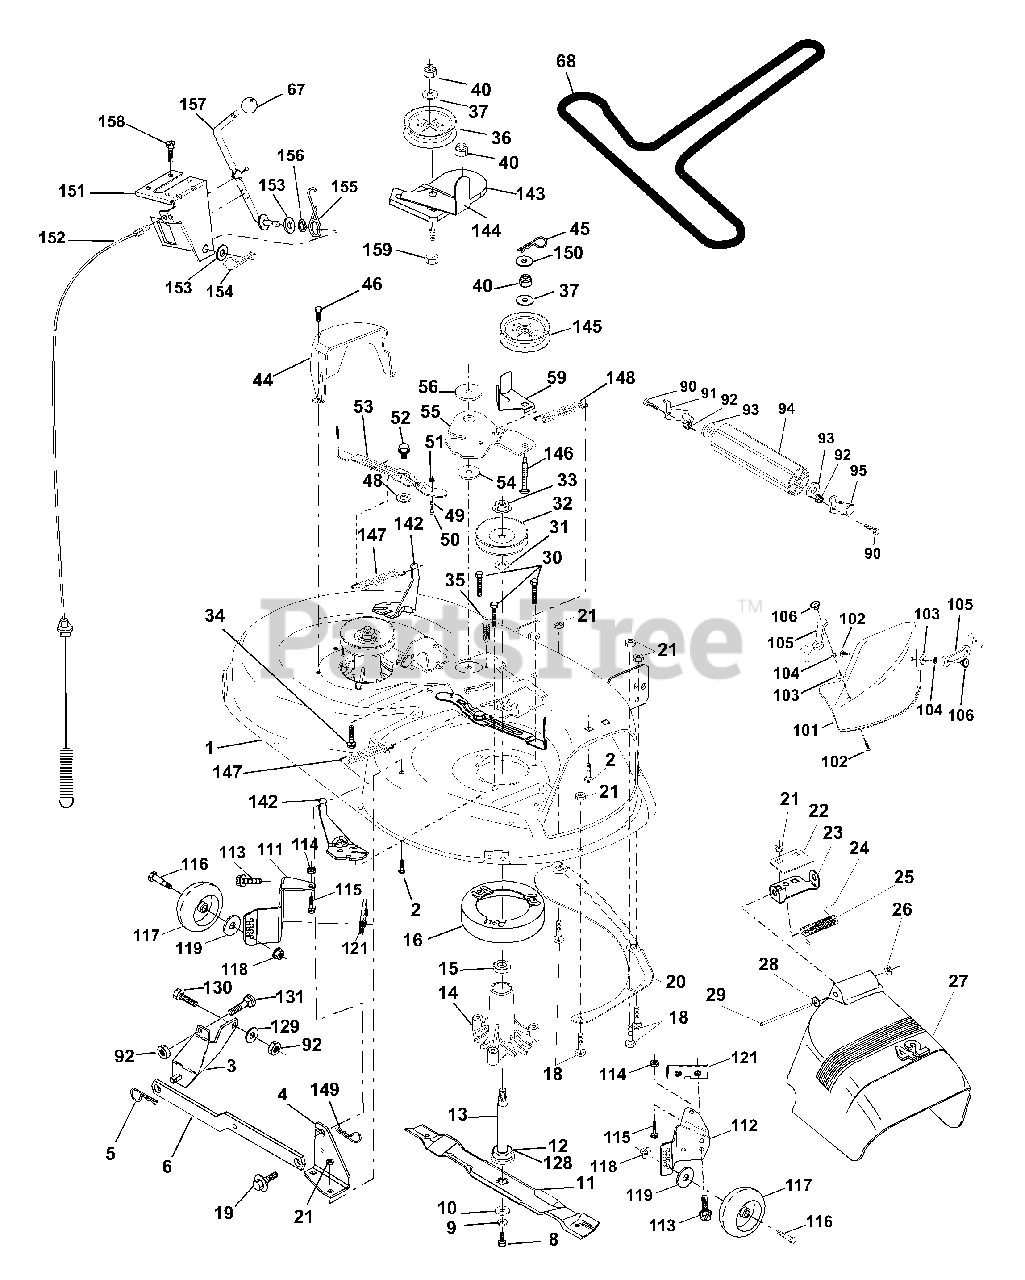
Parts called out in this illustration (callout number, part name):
1	Mower Deck Assembly, 42"
2	Bolt
3	Bracket Asm Fr. Sway Bar 3/42
4	Bracket Asm Deck 42" Sway Bar
5	Retainer Spring
6	Arm, Suspension, Rear
8	Bolt 3/8-24 x 25 Grade 8 patched
9	Washer, Lock
10	Washer,Hardened
11	Blade, Mulching 42" Std
11	Blade Mower 42" Hi-Lift Std
12	Bearing, Ball #6204
13	Shaft Assembly, Mandrel, Vented
14	Housing, Mandrel, Vented
15	Bearing, Ball, Mandrel
16	Stripper, Vented Mower Deck
18	Bolt, Carriage 5/16-18 x 5/8
19	Bolt, Shoulder
20	Baffle, Vortex
21	Nut
22	Stiffener Bracket
23	Bracket, Deflector Mower 42"
24	Cap, Sleeve 80 x 112 Blk Mower
25	Spring, Torsion, Deflector 2 52
26	Nut, Push Phos & Oil
27	Shield, Deflector 42" Blk
28	Washer 11/32 x 5/8 x 16 Gauge
29	Rod, Hinge 42" 6 75 W/G
30	Screw Thdrol Washer Head
31	Washer, Spacer Mower Vented
32	Pulley, Mandrel
33	Nut, Toplock 9/16
34	Bolt
35	Fastener, Christmas Tree
36	Pulley, Idler, Flat
37	Washer 13/32 x 13/16 x 16 Gauge
40	Nut
44	Guard, Mandrel, LH
45	Retainer
46	Screw, Thdrol 1/4-20 x 5/8 T
48	Washer,Hardened
49	Roller Assembly, Cam Follower
50	Bolt, Shoulder #10-24 Grade 5
51	Locknut
52	Bolt, Shoulder 5/16-18 UNC
53	Arm Assembly, Pad, Brake
54	Washer,Hardened
55	Arm, Idler
56	Spacer, Retainer
59	Guard TUV Idler
67	Knob Round
68	V-Belt, 42" Mower
90	Bolt Fin Hex 3/8-16 Unc x 1
91	Bracket Asm Noseroller LH
92	Nut, Lock, Hex W/Ins 3/8-16 UNC
93	Washer 17/3 x 7/8 x 6 Ga.
94	Roller Nose 38 & 42
95	Bracket Asm Noseroller RH
101	Mulcher Cover
102	Screw
103	Washer, Flat
104	Washer, Lock
105	Latch Assembly
106	Nut, Weld
111	Bracket, Gauge, Wheel LH
112	Bracket, Gauge, Wheel RH
113	Screw 5/16 - 18 x 3/4
114	Nut, Keps 5/16 - 18 UNC
115	Bolt, Carriage 5/16-18 x 1/2
116	Bolt, Shoulder
117	Wheel, Gauge
118	Nut Centerlock 3/8-16
119	Washer 3/8 x 7/8 x 14 Ga.
121	Bracket, Extruded
128	Washer, Felt
142	Arm Spring Brake Mower
143	Bracket Arm Idler 42"
144	Keeper Belt 42" Clutch Cable
145	Pulley Idler Flat
146	Bolt Carriage Idler
147	Spring Extension
148	Spring Return Idler
149	Retainer Spring Yellow
150	Washer 9/32 x 3/4 x 16 Ga.
151	Bracket Clutch Cable
152	Clutch Cable 42"
153	Washer Flat 3/8" Type B
154	Spring Retainer
155	Spring Retention LVR CLTCH CAB
156	Spacer Clutch Cable
157	Rod Clutch Cable 3/8"
158	Screw Hex Thd Cut 1/4-20 x 5/8
159	Bolt Rdhd Sqn 3/8-16 UNC x 1-3/4
